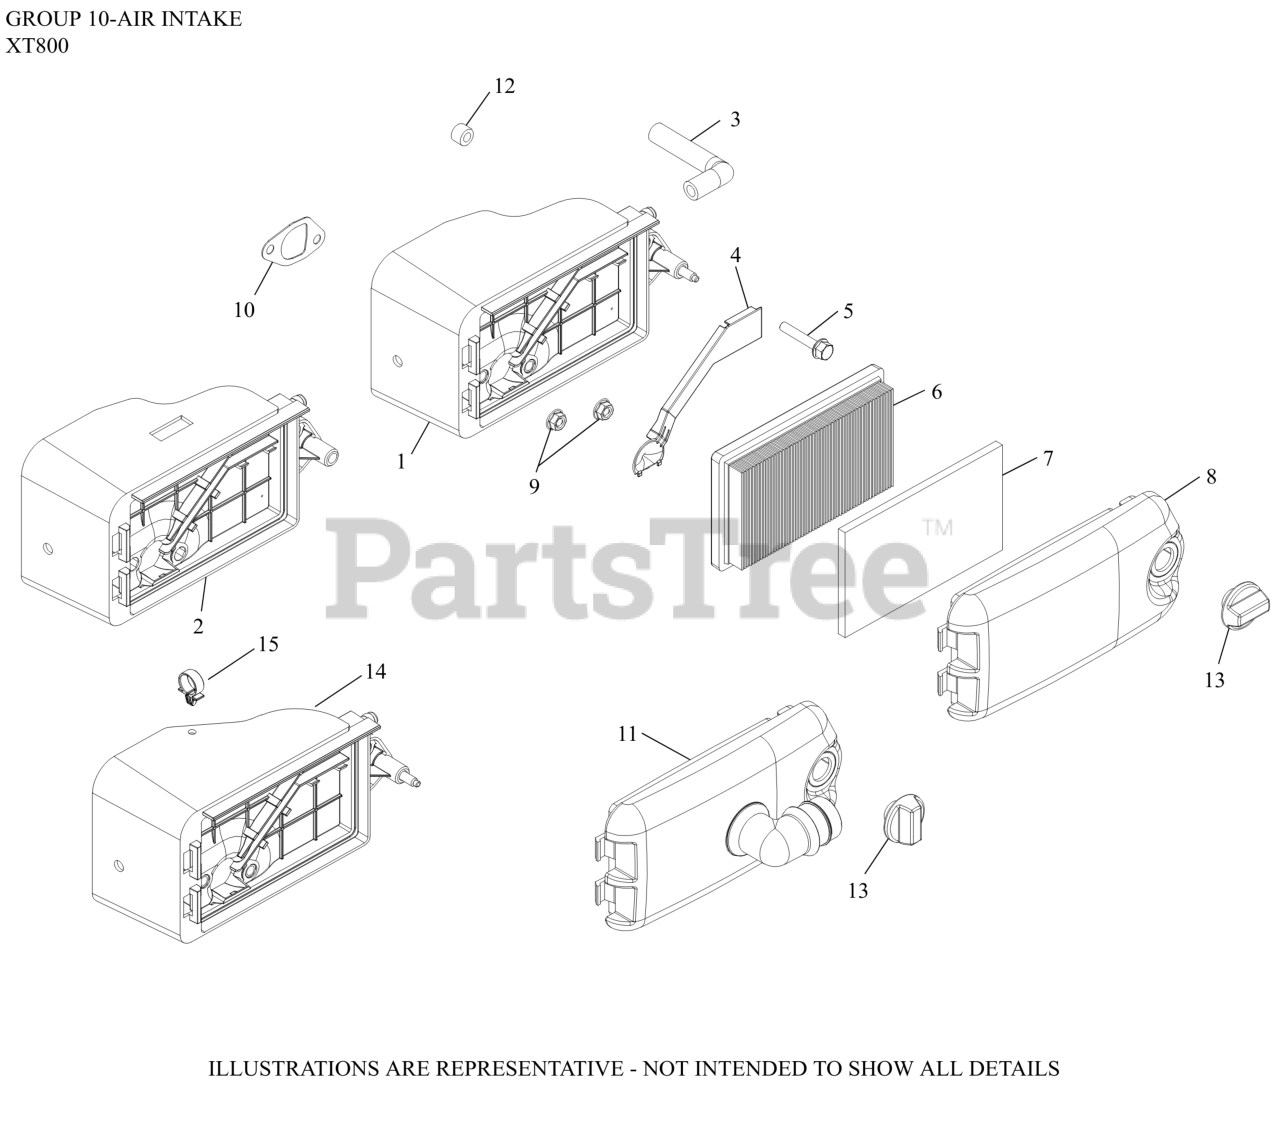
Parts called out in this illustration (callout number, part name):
1	AIR CLEANER BASE-USE 14 094 23-S
3	HOSE, BREATHER
4	COVER, A/C BASE (BREATHER GAS)
5	SCREW, HEX FLANGE (M6)
6	ELEMENT, AIR CLEANER-(#1408319S)
8	COVER, AIR CLEANER
10	KIT, INTAKE GASKET
13	KNOB-USE 14 341 07-S
